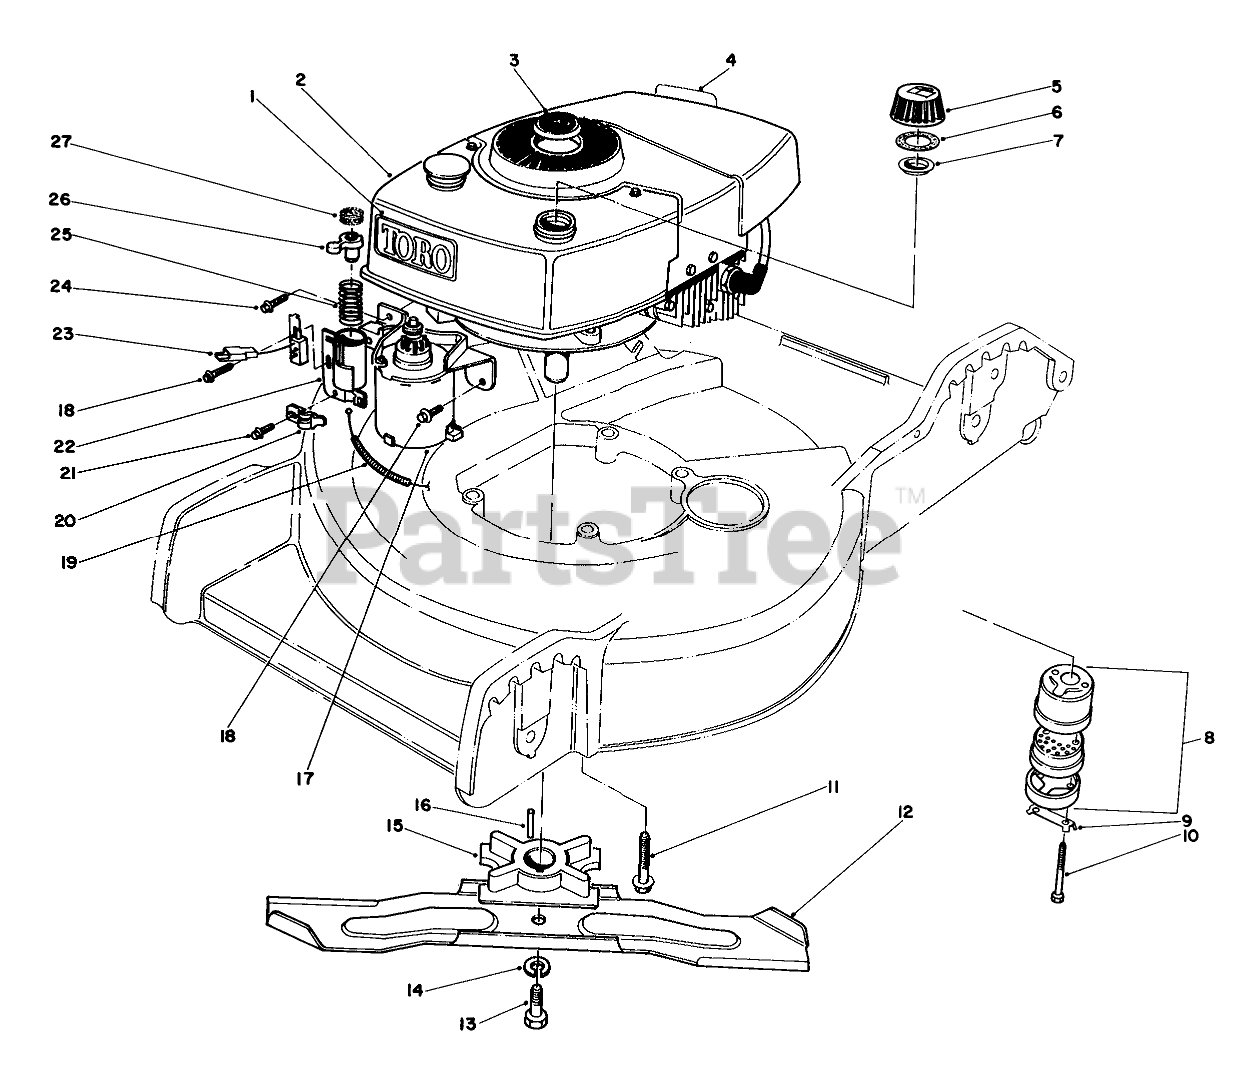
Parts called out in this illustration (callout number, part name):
1	Decal Tow
2	Engine
3	PLUG BUTTON
4	Decal-Maintenan
5	Gas Cap Assembly (Incl. Ref. #6 & 7)
6	GASKET
7	GAS CAP BAFFLE
8	Muffler Assembly (Incl. Ref. #9 & 10)
9	CLIP - LOCKING
10	SCREW-HH
11	3/8-16 X 2 CAPSCREW
12	Blade
13	SPECIAL SCREW
14	WASHER-LOCK
15	Blade Retainer
16	KEY-SQUARE
17	Starter Motor
18	SCREW
19	BRAKE CABLE-SUZUKI
20	CABLE CLAMP
21	SCREW
22	TUBE W A
23	PUSH BUTTON SWITCH
24	Screw
25	COMPRESSION SPRING
26	Plunger
27	Pad-Friction
